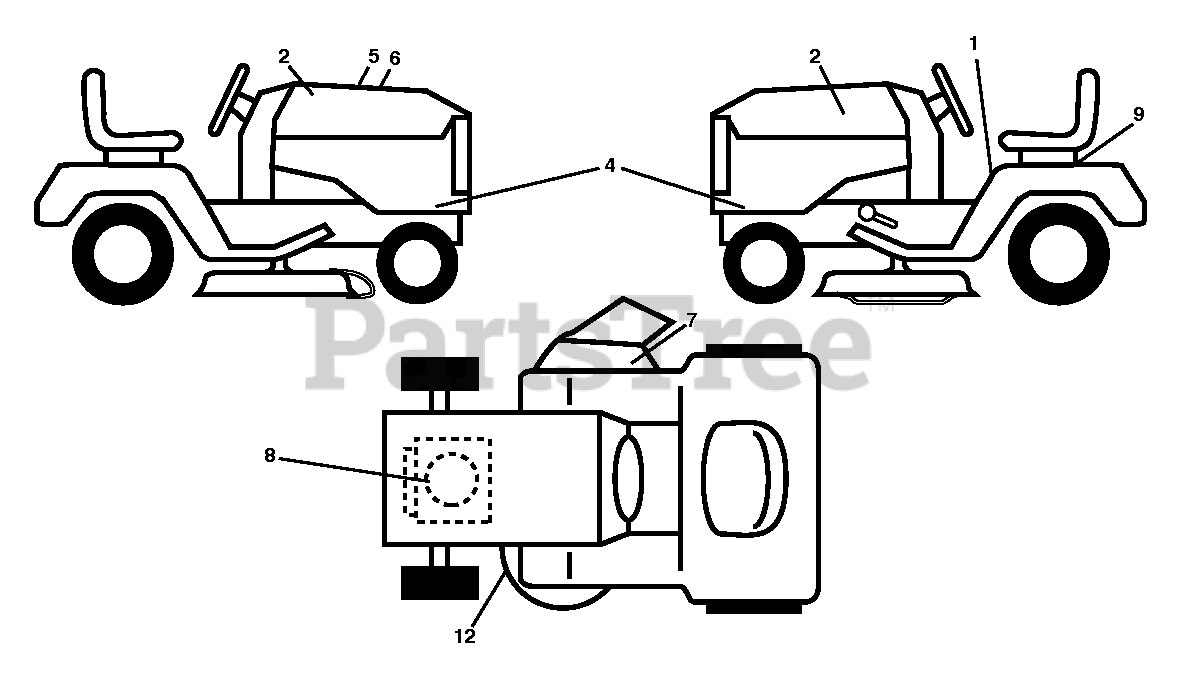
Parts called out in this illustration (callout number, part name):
1	DECAL.FENDER.WARNING.ENGLISH
2	DECAL.BADGE.170MM.TEXTLOGO.
4	DECAL SIDEPANEL
5	DECAL.WARNING.CUST.RESP.E85.
6	Decal, Replacement BSM33 INTK TLW
7	DECAL, DECK DEFLECTOR, WARNING
8	DECAL.ENG.BS.18.5INTK.381713
9	DECAL BTRY SYMBOLS
12	DECAL.V-BELT.SCH.42/46"MEC/ELE
